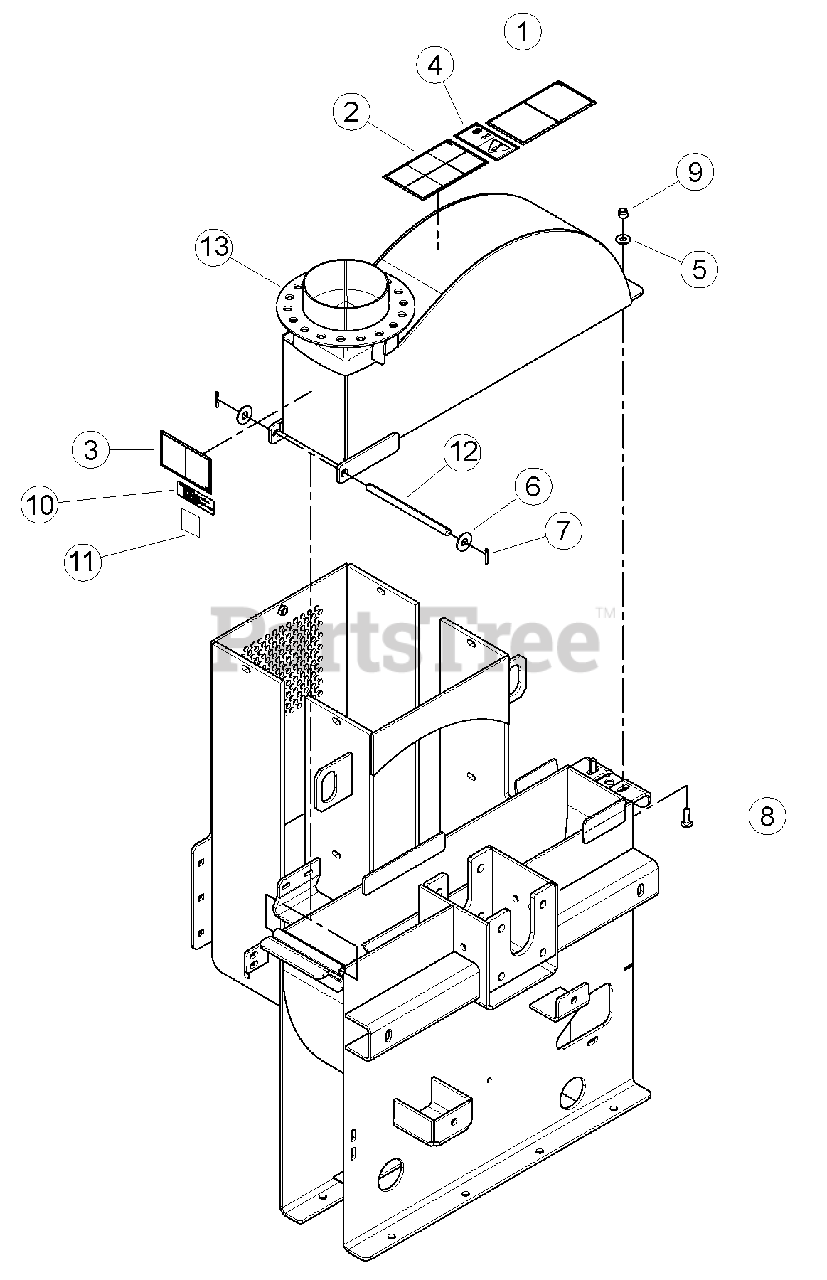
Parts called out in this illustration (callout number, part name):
1	DECAL, KNIFE ACCESS ISO
2	DECAL, OPERATING INSTRUCTIONS ISO
3	DECAL, DISCHARGE ISO
4	DECAL, MAINTENANCE ISO
5	WASHER, 3/8 FLAT ZP
6	WASHER, 1/2 FLAT ZP
7	PIN, 1/8 X 1.00 COTTER ZP
8	BOLT, 3/8 X 1-1/4 CRG GR5 NC ZP
9	NUT, 3/8 NE NYLOCK ZP
10	DECAL, ATLANTIC BRIDGE LTD INFO (CE COMPLIANT ONLY)
11	DECAL, ECHO BEAR CAT QR CODE
12	SHAFT, CHIPPER TOP PIVOT
13	WELDMENT, CHIPPER TOP
